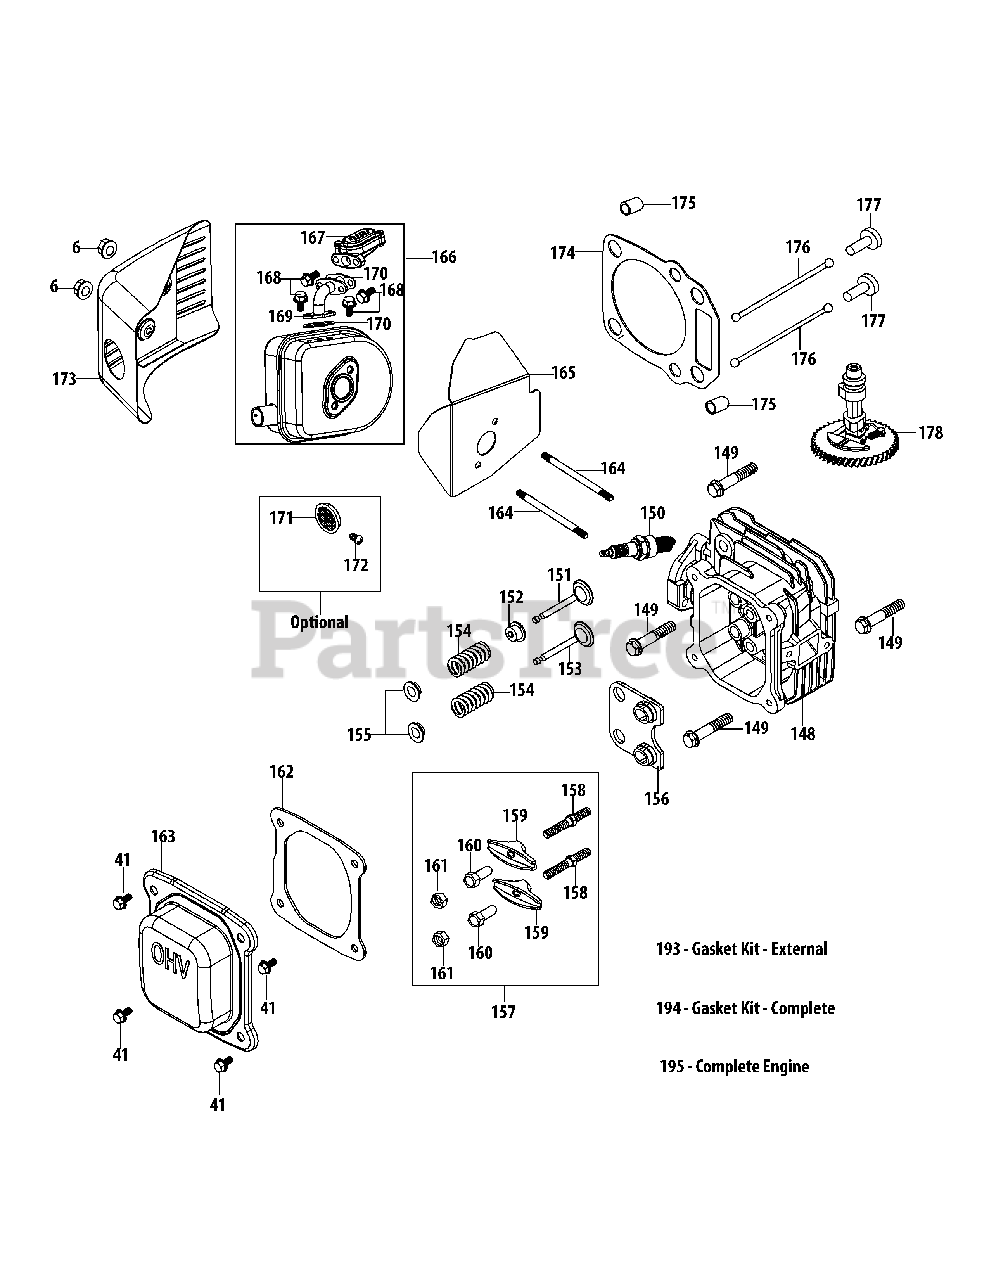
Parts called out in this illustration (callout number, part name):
6	Nut M6X10Mm
41	Bolt M6X14 Multi-Purpose
148	Cylinder Head Assembly
149	Bolt M8X54
150	Spark Plug
152	Intake Valve Seal
154	Valve Spring
155	Valve Spring Retainer
156	Push Rod Guide
157	Rocker Arm Assembly
158	Rocker Arm Stud
159	Rocker Arm
160	Fulcrum Nut
162	Valve Cover Gasket
163	Valve Cover
164	Muffler Stud M6X95
164	Muffler Stud Assemlby
165	Muffler Gasket
166	Muffler Assembly
167	Secondary Air Valve
168	Bolt M6×12
169	Secondary Air Tube
170	Secondary Air Valve Gasket
171	Spark Arrestor
172	Spark Arrestor Screw
173	Muffler Shield
174	Cylinder Head Gasket
175	Cylinder Head Dowel Pin 10×16
176	Push Rod Kit
178	Camshaft Assembly
193	Gasket Kit - External
194	Gasket Kit - Complete
195	Complete Engine
